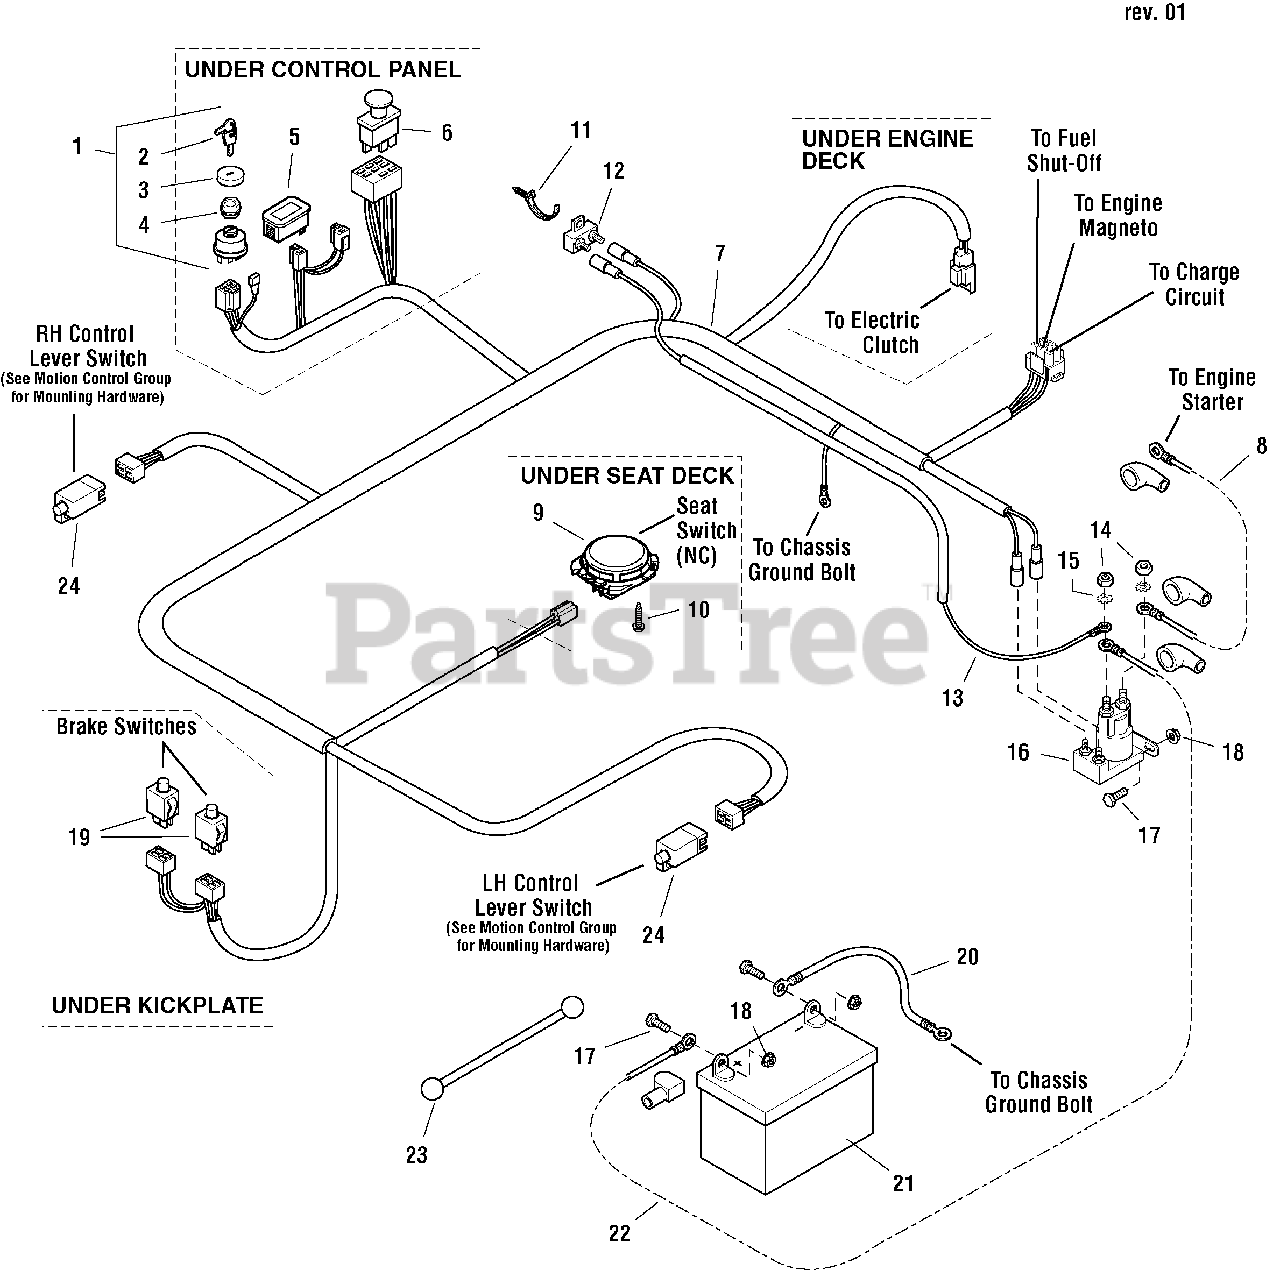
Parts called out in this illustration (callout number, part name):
1	SWITCH ASMY-IGNITION INDAK NO KEYS
2	KEYS. BLISTER PK KIDS+MWRS DON'T MIX, USA Models Only
3	COVER, PLASTIC, SNAP ON
4	PLASTIC NUT
5	HOUR METER, DIGITAL
6	SWITCH, PTO
7	MAIN HARNESS ASSEMBLY
8	CABLE, #6 X 15" LONG, RING TERMINAL
9	SWITCH, SEAT, GRAY, NC (Twist in)
9	SWITCH, SEAT (Screw in)
10	BOLT, HEX WASHER HEAD PLASTITE, 1/4 X 1/2
11	CABLE TIE, PUSH MOUNT
12	CIRCUIT BREAKER, 20A
13	CRICUIT BREAKER WIRE ASSEMBLY
14	NUT, HEX JAM, 5/16-24
15	WASHER, LIGHT LOCK, 5/16
16	SOLENOID
17	BOLT, 1/4-20 X 3/4
18	NUT, HEX SERRATED FLANGE, 1/4-20
19	SWITCH, DP NO/NC SNAP-IN
20	CABLE, #6 X 22" LONG, RING TERMINAL
21	BATTERY, 12 VOLT
22	CABLE, #6 X 30" LONG, RING TERMINAL
23	STRAP, BATTERY, 14 LONG, RUBBER
24	SWITCH, PLUNGER, N.O./N.C.
